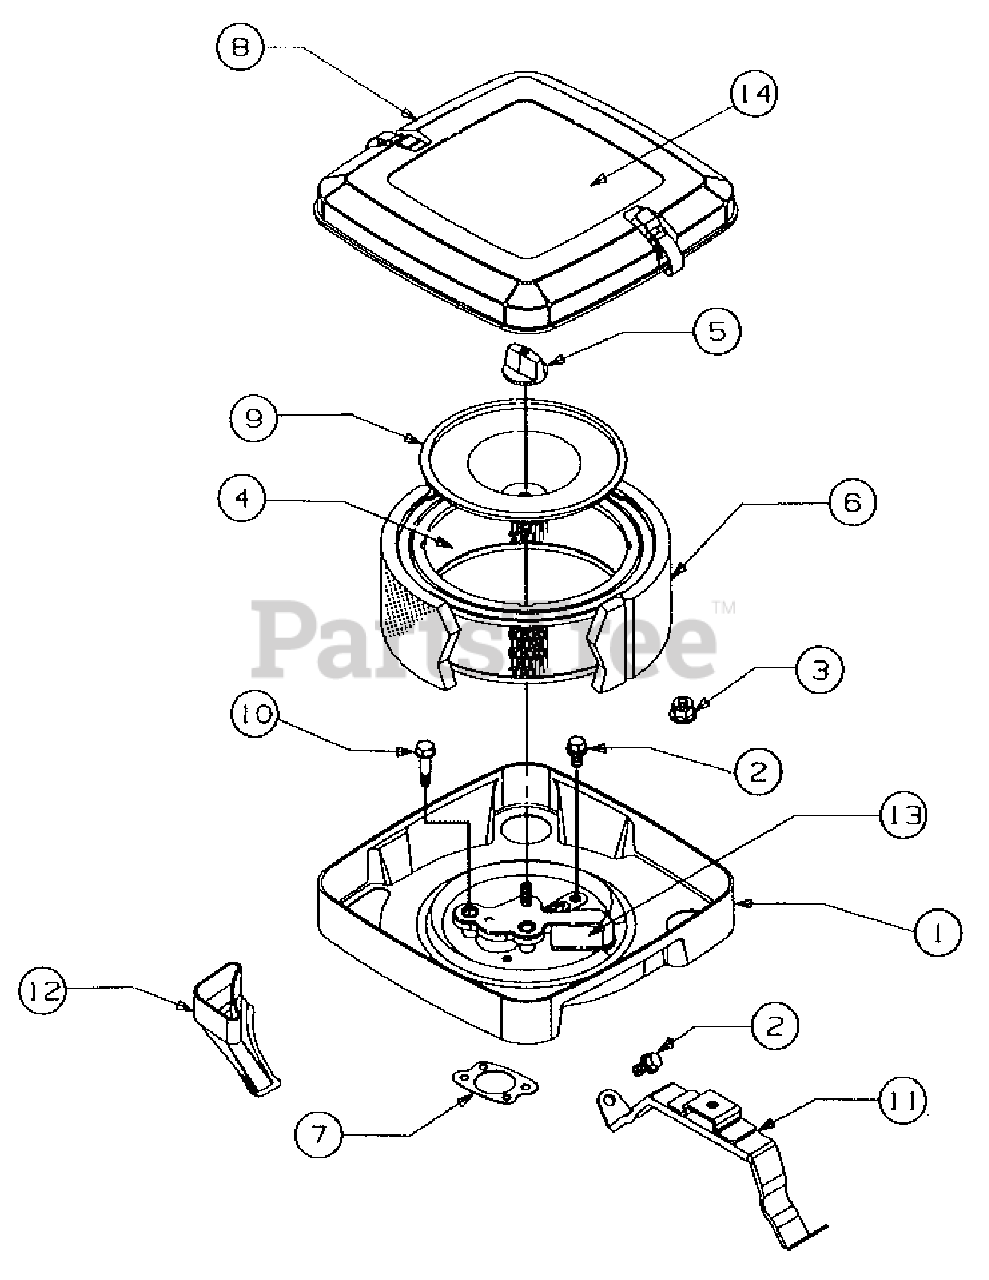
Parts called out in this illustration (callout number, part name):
1	Base Assembly, Air Cleaner
2	Screw, Sem
3	Nut, Hex Washer Hd
4	Cartridge, Air Filter
5	Knob, Air Clener
6	Element, Pre-Cleaner
7	Gasket, Air Cleaner
8	Cover Assembly, Air Cleaner
9	Plate, Air Filter
10	Screw, Sem
11	Bracket, Air Cleaner
12	Tube, Air Inlet
13	Deflector, Air Cleaner
14	Label, V-Twin Engine
